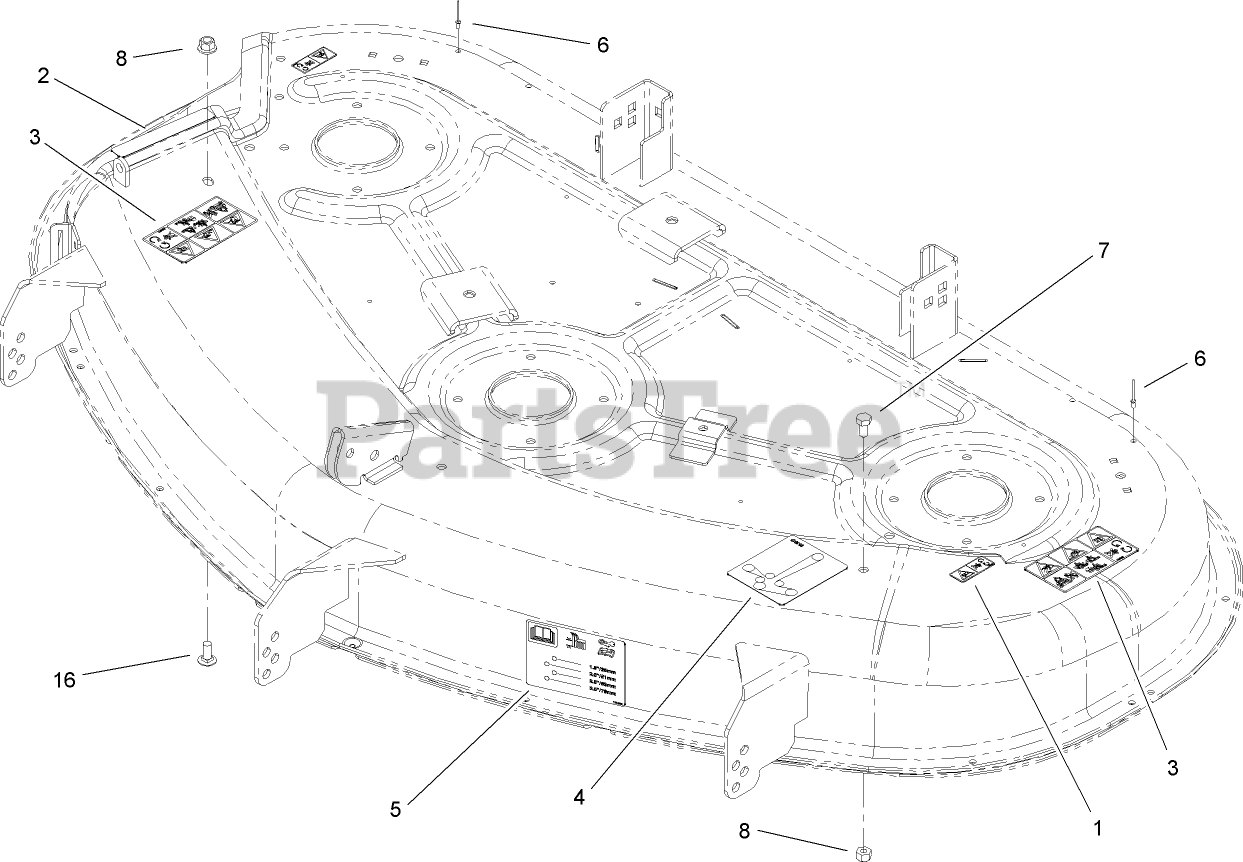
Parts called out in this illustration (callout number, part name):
1	DECAL-DANGER
2	DECAL-DANGER
3	DECAL-DANGER
4	DECAL-ROUTING, BELT
5	DECAL-SCALP, ANTI
6	RIVET-BLIND
7	SCREW-HH
8	NUT-LOCK, NI
16	SCREW-CARR
